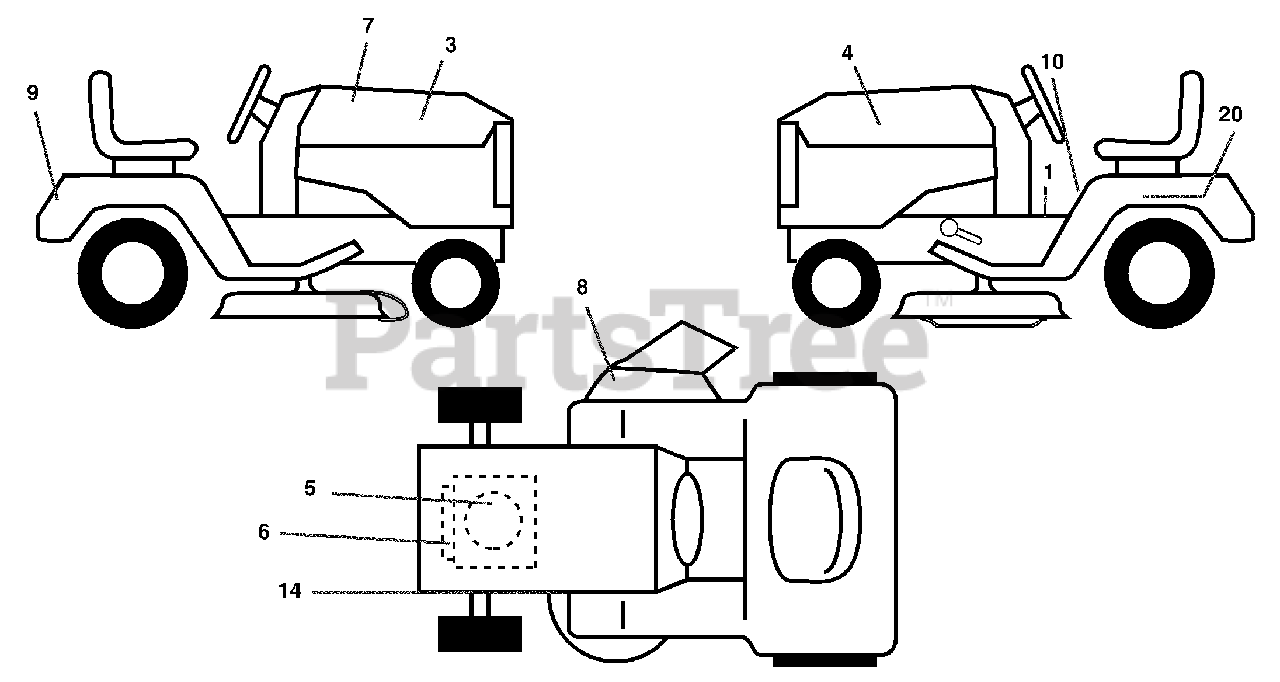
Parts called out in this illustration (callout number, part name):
1	Decal Oper. Step Thru Eng/Fr
3	Decal Hood RH
4	Decal Hood LH
5	Decal Hood Cust.
6	Decal Engine
7	Decal Replacement
8	Decal Warning
9	Decal Fender
10	Decal Fender Danger Eng/Fr
14	Decal V-Belt Schematic
20	Decal Bat Dan/Psn
